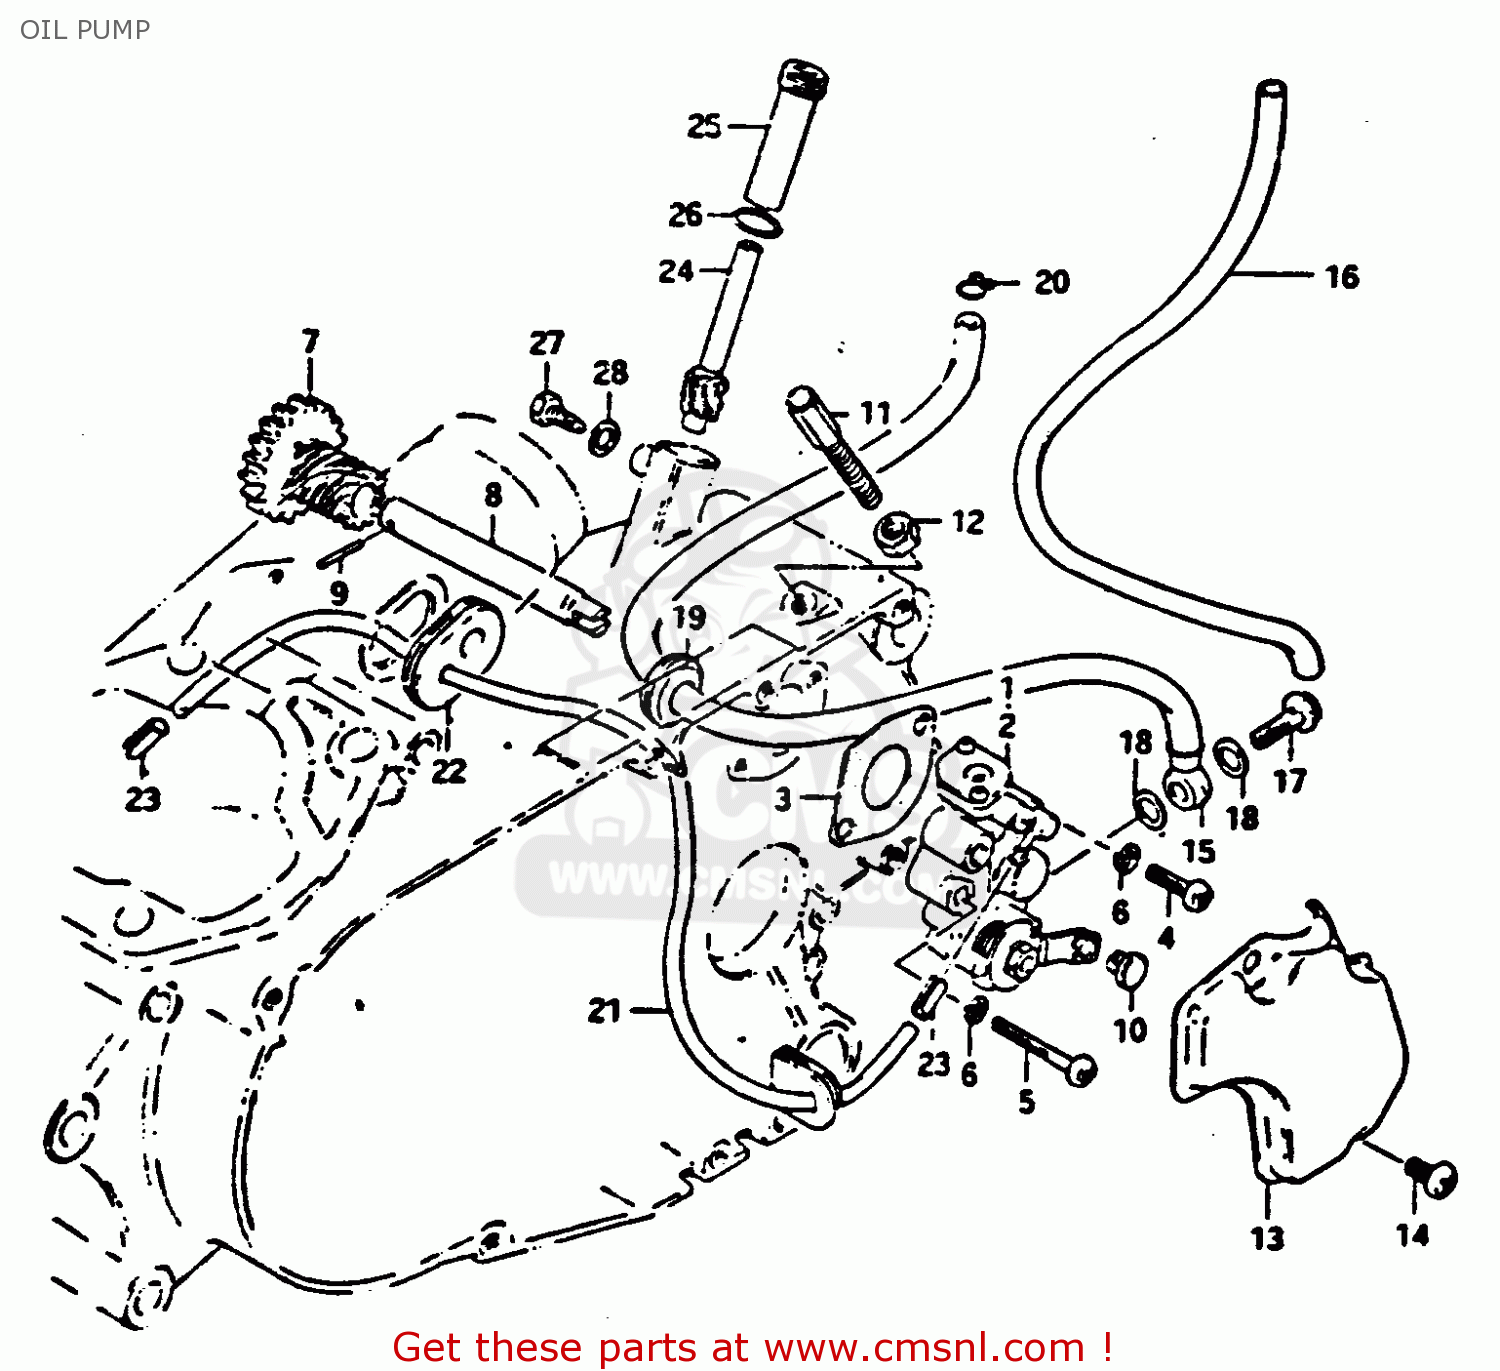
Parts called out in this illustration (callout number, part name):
1	PUMP ASSY, OIL
2	PUMP ASSY,OIL
3	GASKET,OIL PUMP (NAS)
4	SCREW
5	SCREW
6	LOCK WASHER
7	GEAR,OIL PUMP DRIVE
8	SHAFT,OIL PUMP DRIVE GEAR
9	PIN(2.5X19.8)
10	TERMINAL,CABLE
11	BOLT
12	NUT
13	CAP,OIL PUMP INSPECTION
14	SCREW
15	HOSE,OIL NO.1
16	HOSE (4.5X8.5X600)
17	UNION BOLT
18	GASKET(6.2X11X1).2 (NAS)
19	GROMMET
20	CLIP
21	HOSE,OIL NO.2
22	GROMMET,OIL HOSE NO.3
23	CLIP
24	GEAR, TACHO. DRIVEN (NT:10)
25	SLEEVE,TACHOMETER DRIVE GEAR
26	O RING(D:1.3,ID:9.6)
27	BOLT
28	WASHER
